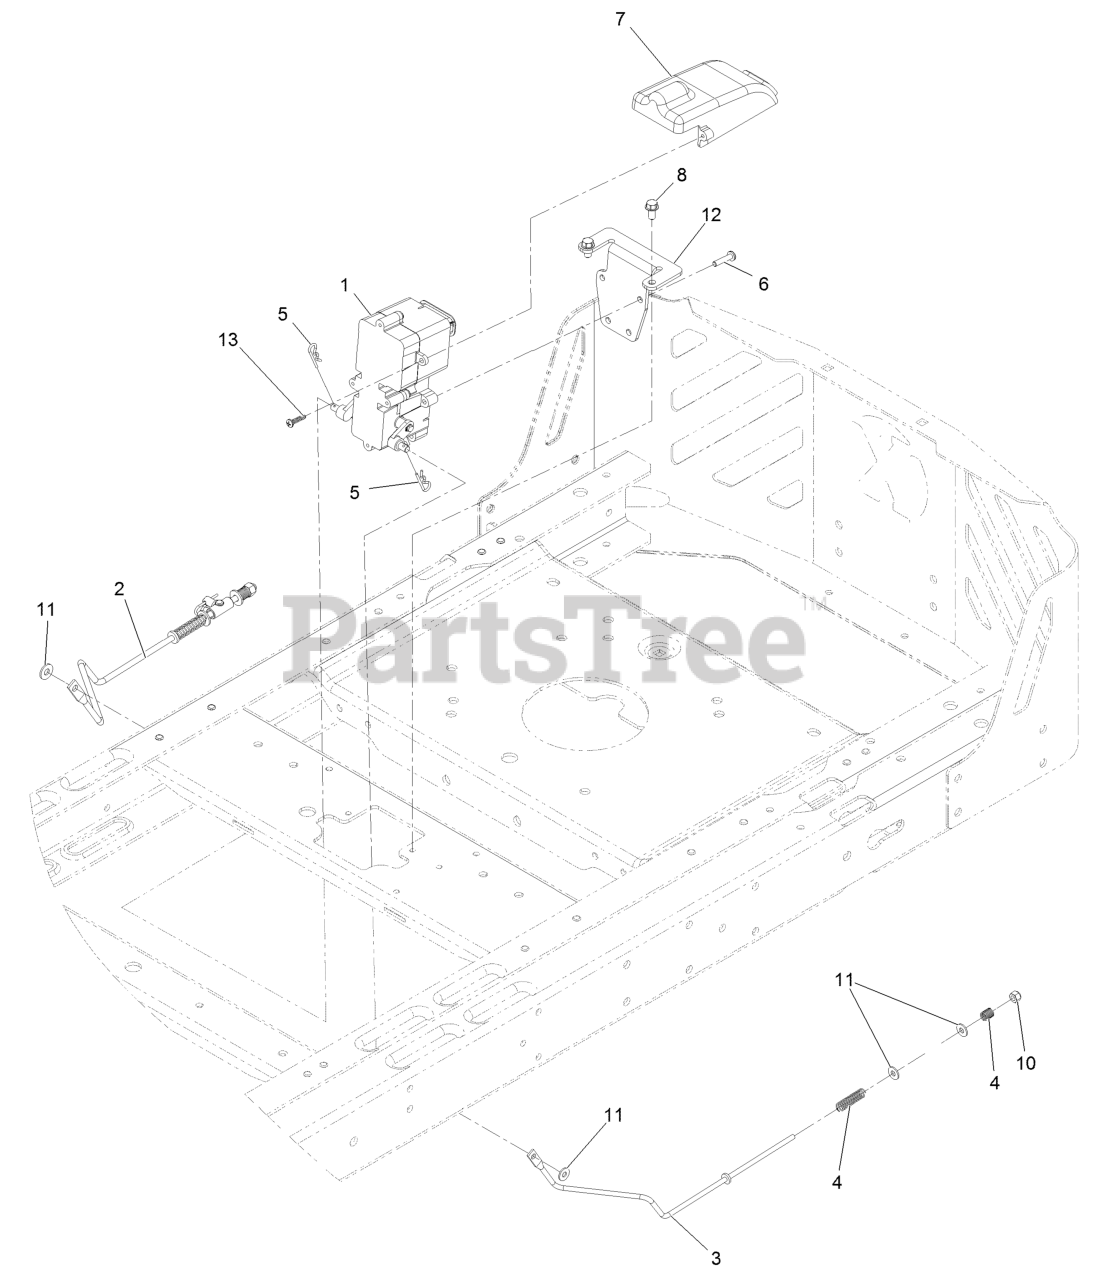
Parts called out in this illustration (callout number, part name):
2	ROD-BRAKE, WIDE (RH)
3	ROD-BRAKE, WIDE (LH)
4	SPRING-COMPRESSION
6	SCREW-PPH
7	COVER-CONNECTOR
8	SCREW-HWH
10	NUT-LOCK, NI
12	BRACKET-MOUNT, BRAKE
13	SCREW-PPH
